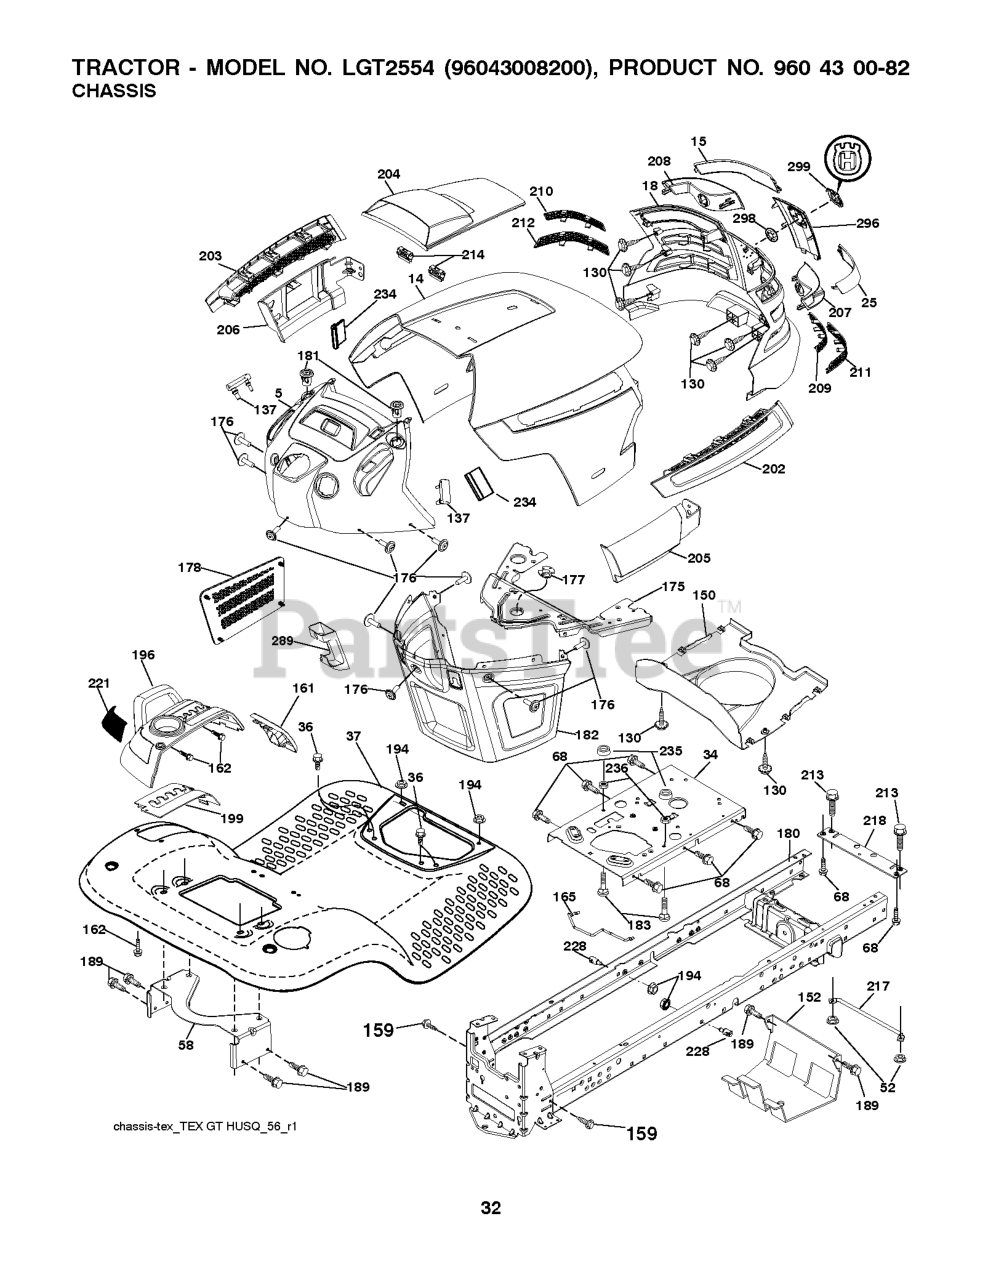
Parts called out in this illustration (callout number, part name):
5	DASH.ASM.HUSQ.GT.E.RECT.W/CK
14	HOOD
15	LENS.LH.TEX.GT.HUSQ.CL
18	GRILL.ASM.HUSQ.TG/CRD.W/TRIM
25	LENS.RH.TEX.GT.HUSQ.CL
34	PLATE.ENGINE.WELDED.CHASSIS
36	SCREW 5/16"
37	FENDER.PNT.TX.GT.CH/FW.ORANGE
52	LOCKNUT
58	BRKT.SUPPORT.FNDR/TANK
68	Screw 5/16-18 x 1/2 Hex, Self Tapping 5/16-18 x 1/2
130	SCREW.#10 X 0.750.BOS
137	BUMPER DASH
150	AIR.DUCT.HOOD.TEX.GT.HUSQ
152	SHIELD.BROWNING.W/TEX
159	SCREW, 3/8-16X3/4
161	CONSOLE.FUEL.WINDOW.HU
162	SCREW.HI-LO.CONSOLE
165	SUPPORT.TANK.REAR.W/TEX
175	PLATE.CROSSMEMBER.HUSQ
176	SCREW.#10-24X5/8.RN.QU
177	BUSHING, STEERING
178	CARGO.ASM.NET.TXGT.W/C
180	CHASSIS.GT.SLOPED.DRAWBAR.
181	BUSHING.MNT.FEND.CRGO.
182	DASH.LOWER.COMMON.12V.ADAPTOR
183	BOLT.5/16-18X1-1/4 FULL.THREAD
189	SCREW
194	NUT LOCK HEX FLANGE 5/16-18
196	RP CONSOLE.ASM.DECKLFT.W/
199	PLATE.DECK.LIFT.HUSQVARNA.GT
202	VENT.SIDE.HOOD.HUSQ.RH.GREY
203	VENT.SIDE.HOOD.HUSQ.LH.GRAY
204	HOOD VENT
205	SKIRT.HOOD.SIDE.HUSQ.RH.GREY
206	SKIRT.HOOD.SIDE.HUSQ.LH.GREY
207	BEZEL.RH.TEX.GT.HUSQ
208	BEZEL.LH.TEX.GT.HUSQ
209	INSERT.HEX.GRILL.HUSQ.GREY
210	INSERT.HEX.GRILL.HUSQ.
211	INSERT.HEX.GRILL.HUSQ.
212	INSERT.HEX.GRILL.HUSQ.
213	BOLT
214	CLIP.RETAINER.TINNER.
217	ROD.PIVOT.HOOD
218	X-PIECE.HOOD.STOP.NON/
221	REFLECTOR.LH.TEX GT HU
228	STUD.FASTNER.W/ANTI-ROTATE
234	BUMPER.HOOD.TEX.HUSQVARNA
235	SPACER FENDER
236	NUT.CENTERLOCK.5/16-
289	PLUG.N/CRUISE.COMMON.YT/GT.BLK
296	TRIM.HUSQ.TG/CRD.SERVICE
298	NUT PUSH M
299	RP LOGO
